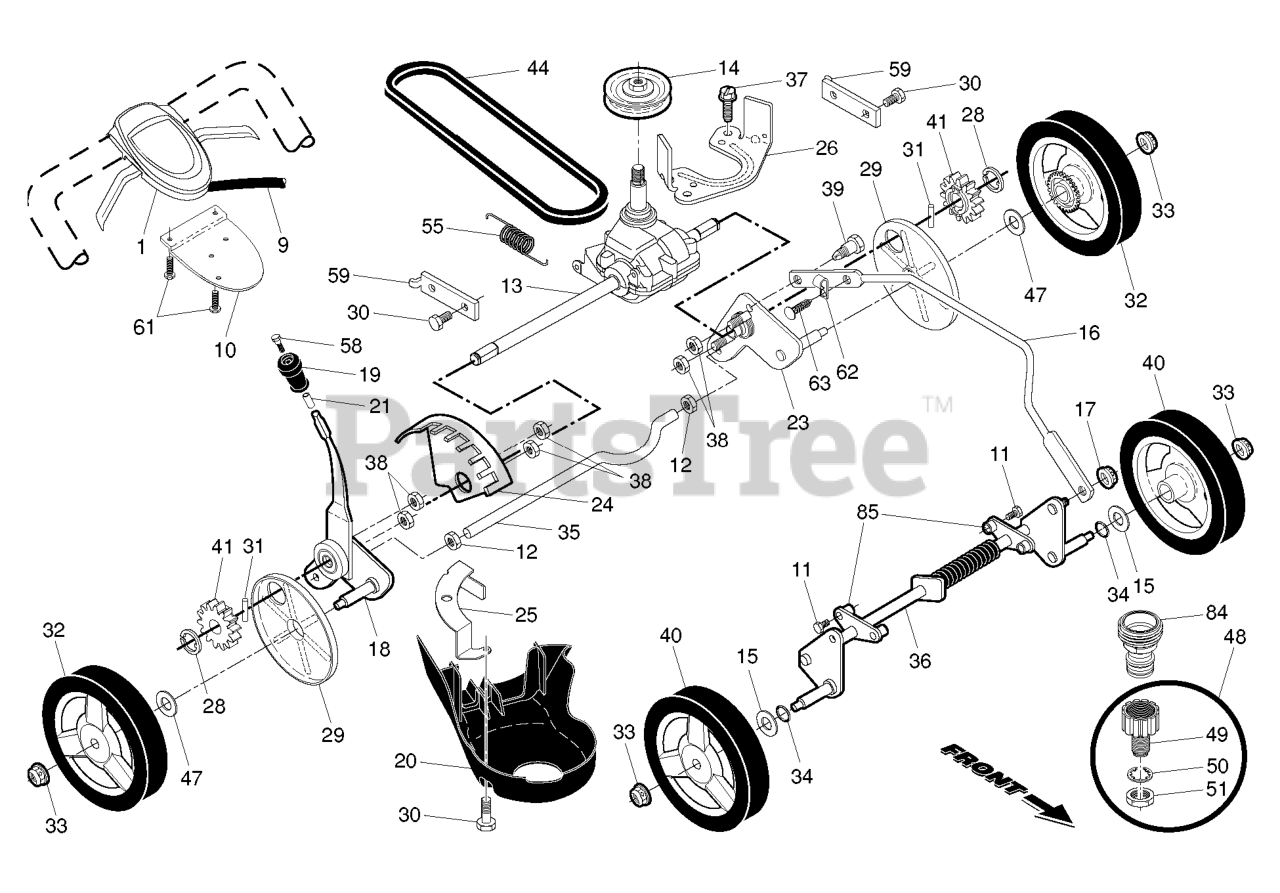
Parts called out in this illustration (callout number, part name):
1	RB CTRL.AW2.22+RGD.BS.GRY/BLK
9	CABLE.CONTROL.22RGD.GEN2
10	BRACKET.DRIVE.CONTR.GEN2.BLACK
11	SCREW.HX.13X.750
12	NUT.HEX.1/2-20
13	RP TRANSMISSION.22+.RGD.AW2/
14	PULLEY.1.PIECE
15	WASHER.FLAT.1/2
16	ROD.CONNECTING.RGD.22+.HW.BLAC
17	NUT.LOCK.5/16-18
18	SELECTOR.ASM.22.PLUS
19	KNOB.SEL.SPRING.22+.SP.RIB.BLK
20	RP.COVER.REAR.DRIVE.22+
21	SCREW.PLASTIC.ANCHOR.5/16
23	ADJUSTER.ARM.ASM.AX.RT.SP.ZC
24	BRACKET.WHL.ADJ.9.POS.W/PAD
25	BRACKET.DRIVE.COVER.RGD.BZP
26	BRACKET.TRANS.BELTKEEP.22+RGD
28	E-RING 7/16 RE
29	COVER.DUST.WHEEL
30	BOLT.5/16HEX.WHS.HD
31	PAWL, DRIVE
32	KIT.WHEEL.442789X460.8"
33	NUT.HEX.FLANGE.3/8-16.LO(3 2)
34	O-RING..070X.487.NEOPRENE
35	AXLE.REAR.RGD
36	AXLE.ASM.FRONT.RGD.CLEAR.ZINC
38	NUT.HEX.FLANGE.1/4
39	SHOULDER BOLT SEMI GIMLET PT.
40	WHEEL.8IN.H3SPK.ALPHA.
41	PINIION.14.TOOTH.RGD
44	BELT.DRIVE.RGD.BBC
47	WASHER FLUT
48	KIT.WASH-OUT.PORT.ZINC.WALK
49	WASHOUT.PORT.ZINC.RGD.22+
50	WASHER.LOCK.INTERNAL.TOOTH
51	LOCKNUT.HEX.WITH.O-RING
58	SCREW.12-14X1.500
59	BRACKET.SUPPORT.22+RWGD.BZP
61	SCREW, PHILLIPS HEAD 10 X 5/8
62	CLIP.CABLE.BLK
63	FASTENER.PUSH.O.250X0.783
84	COUPLING.QUICK CONNECT
85	BRACKET.FRT.AXLE.SUPPORT
